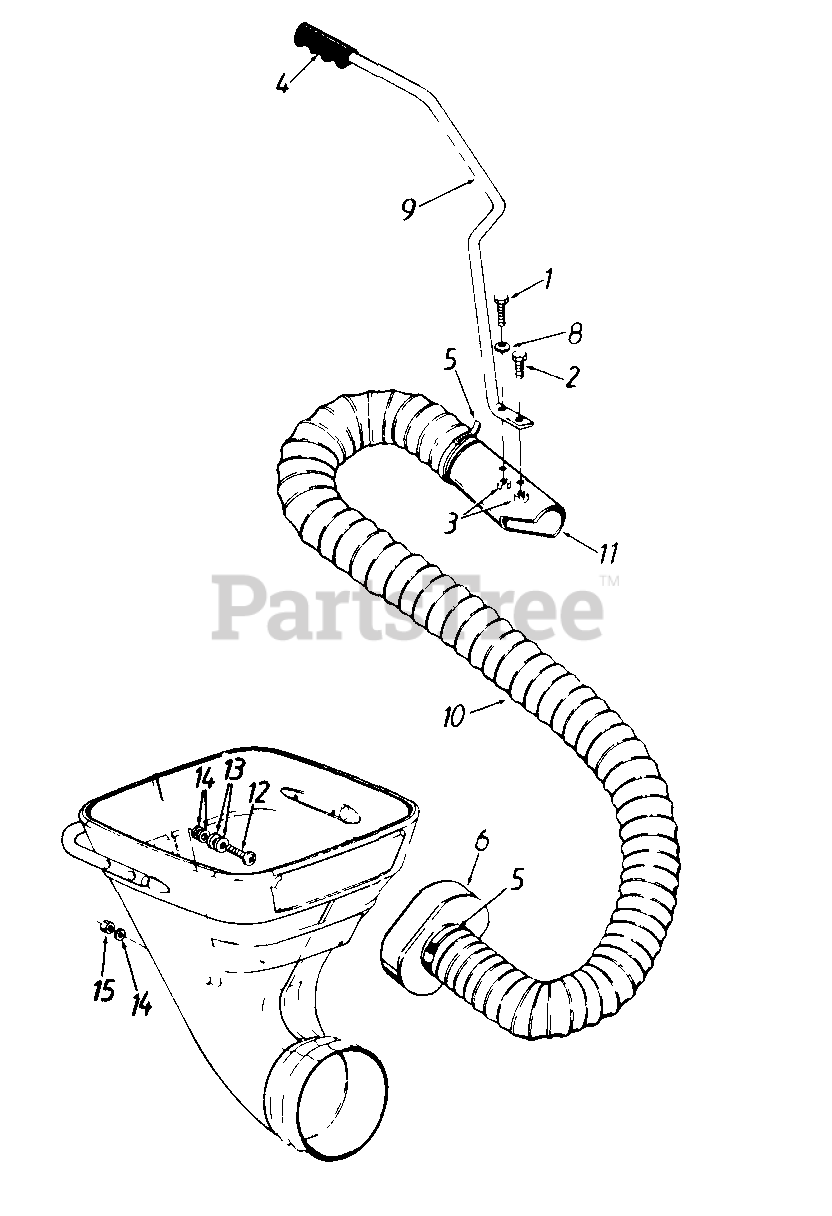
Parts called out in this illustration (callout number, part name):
1	Hex Bolt 1/4-20 x 1.25" Lg.
2	Hex Bolt 1/4-20 x .62" Lg.
3	Hex L-Nut 1/4-20 Thd.
5	Adj. Hose Clamp 5" Dia.
8	Saddle Washer .32" I.D. x .937"
10	Hose - 5" Dia.
11	Nozzle Tube
12	Truss Mach. Scr. 5/16-18 x 3/4" Lg.
13	FI-Wash..344" I.D. x .75" O.D.
14	FI-Wash..328" I.D. x .68" O.D.
15	Hex L-Nut 5/16-18 Thd.
